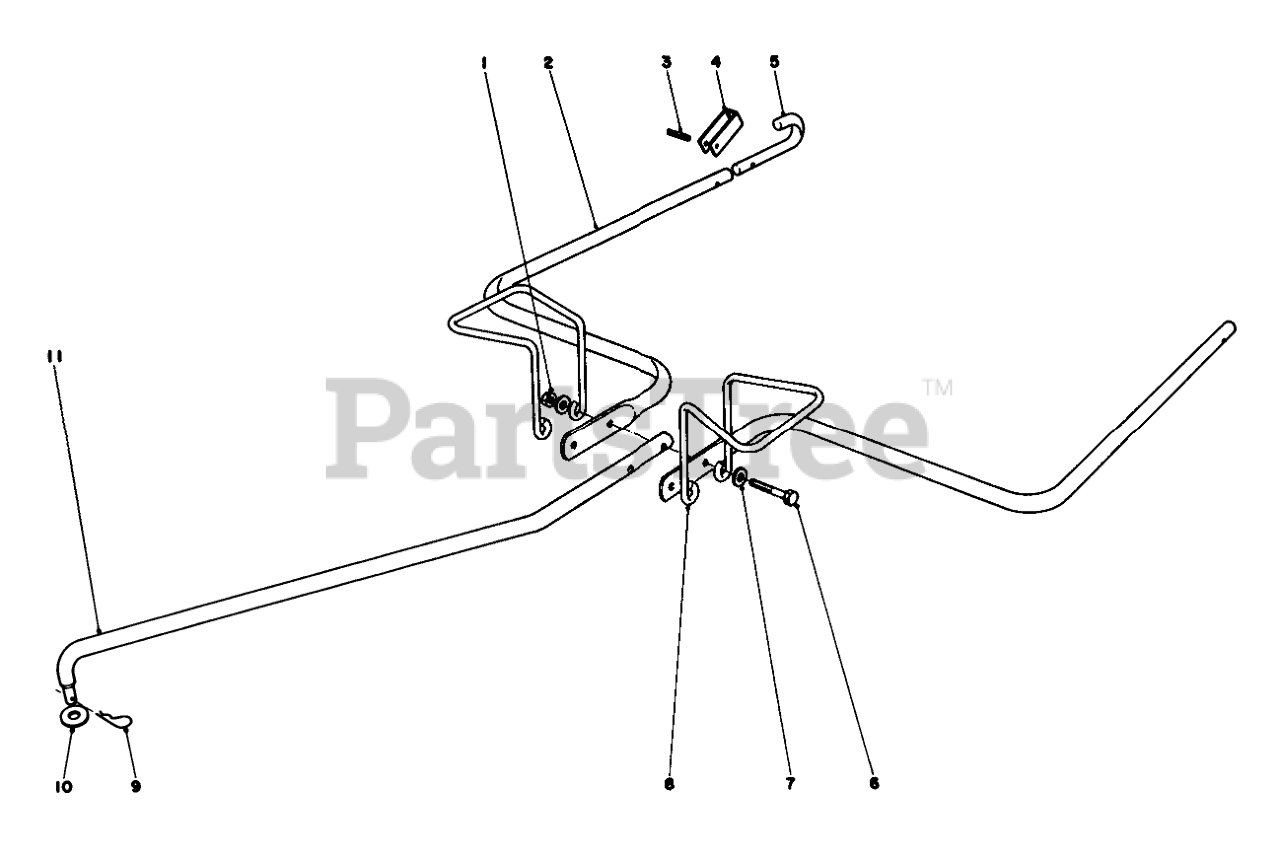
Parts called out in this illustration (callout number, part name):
1	NUT-LOCK, CONE
2	HITCH ARM
3	PIN-ROLL, SLOT
4	HITCH LOCK
5	HOOK HITCH ARM
6	SCREW-HH
7	WASHER-FLAT
8	Support Bag
9	PIN-COTTER
10	PUSH NUT
11	POLE HITCH
